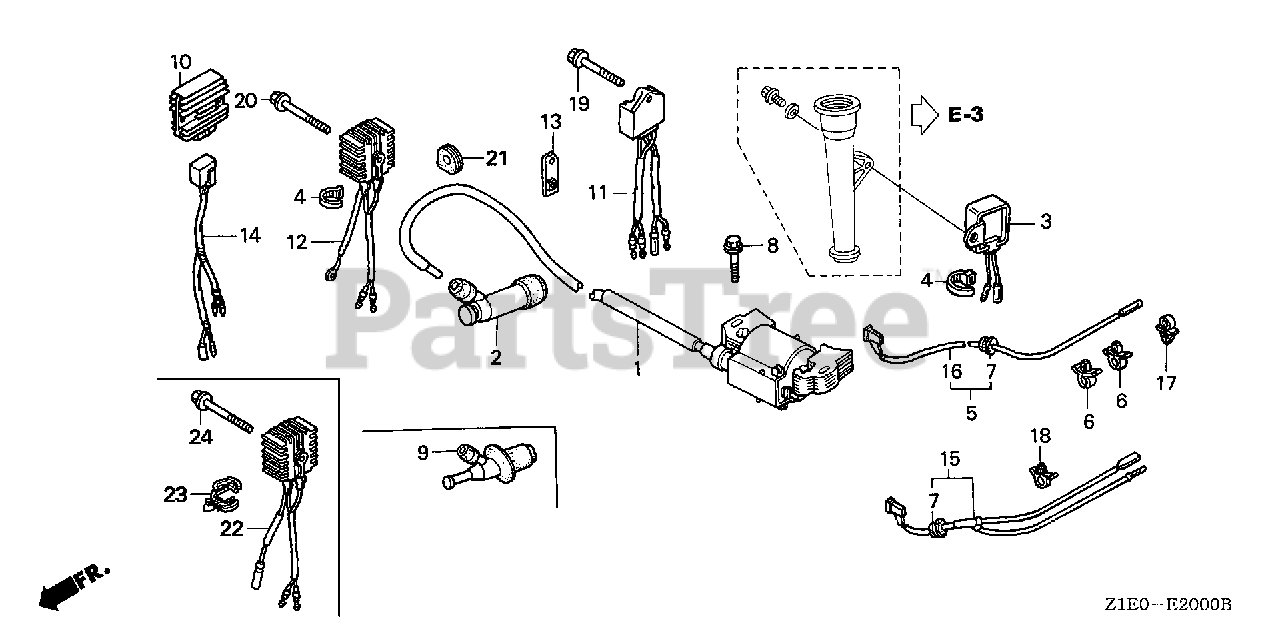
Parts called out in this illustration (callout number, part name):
1	COIL ASSY., IGNITION
2	CAP ASSY., NOISE SUPPRESSOR
6	CLIP, BRAKE PIPE (A) (FOR NEUTRAL SWITCH)
7	GROMMET, WIRE
8	BOLT, FLANGE (6X28) (CT200) Use up to Engine SN 1530314.
15	WIRE, STOP SWITCH
17	HOLDER, WIRE (FASTEX)
21	GROMMET, WIRE
22	RECTIFIER ASSY., SILICON
23	CLIP, WIRE HARNESS
24	BOLT, FLANGE (6X40)
